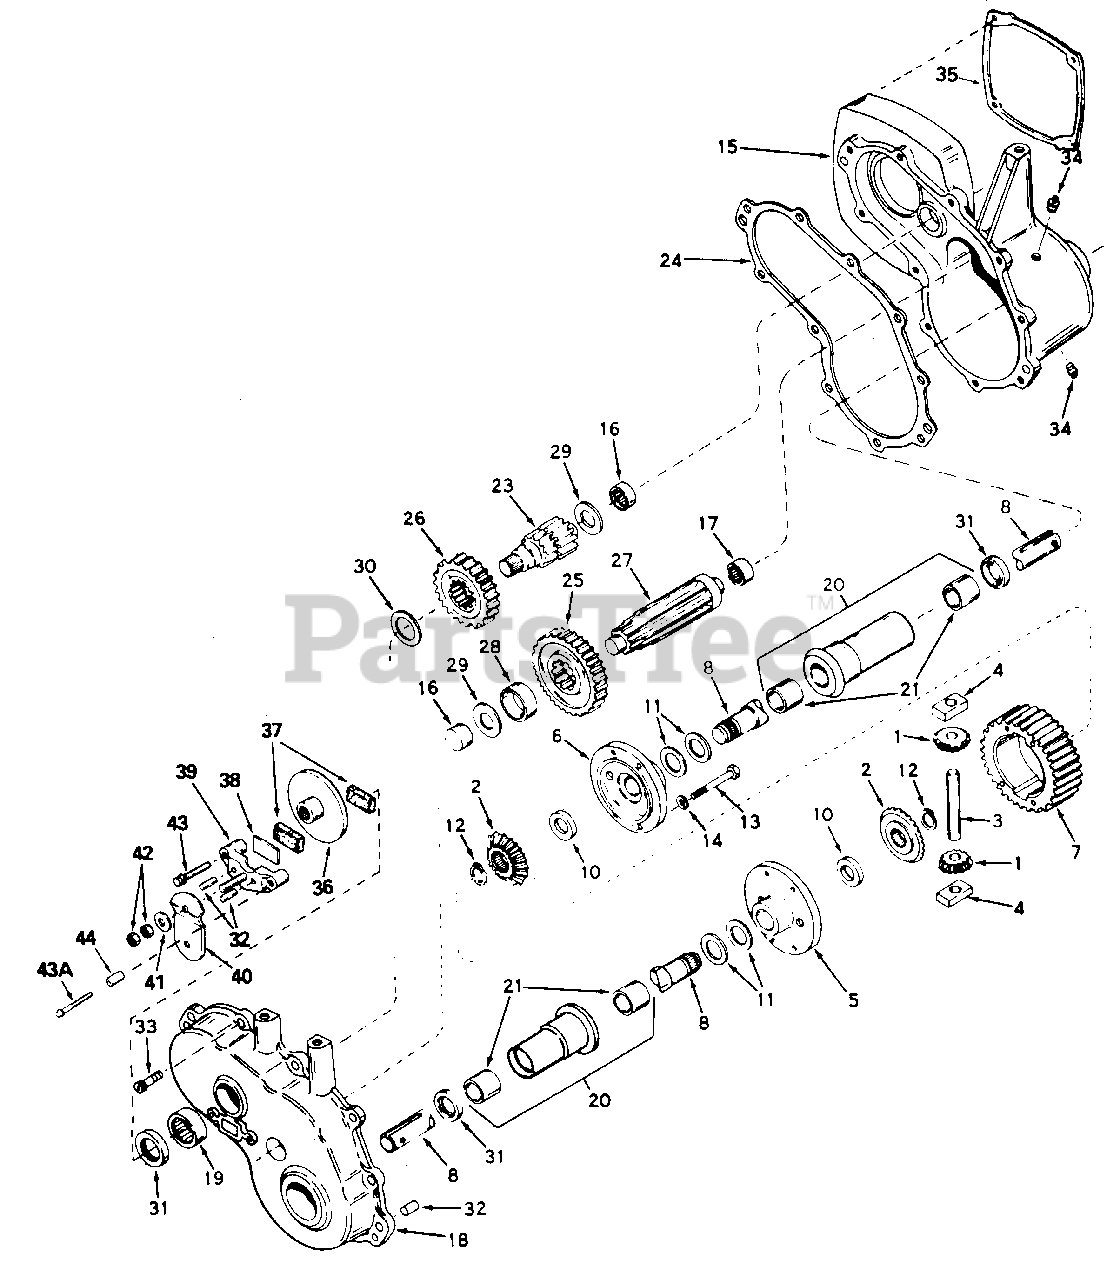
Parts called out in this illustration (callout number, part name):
1	Pinion, Bevel
2	Gear, Bevel
3	Pin, Drive
4	Block, Drive
5	Carrier, Differential
6	Carrier, Differential
7	Gear, Ring
8	Axle (16-1/64" Long)
10	Washer
11	Washer, Thrust
12	Ring, Snap
13	Screw, Hex Hd. 1/4-20 x 2-1/4
14	Lock Washer, 1/4"
15	Case Ass'y.
16	Bearing, Needle
17	Bearing, Needle
18	Cover Ass'y.
19	Bearing, Needle
20	Housing Ass'y., Axle
21	Bushing
23	Shaft, Brake
24	Gasket, Case to Cover
25	Gear, Output
26	Gear, ldler
27	Shaft, Output
28	Spacer
29	Washer
30	Washer
31	Seal, Oil
32	Pin, Dowel
33	Screw, Hex Hd., Self-Tapping, 1/4-20 x 1
34	Plug, Pipe
35	Gasket
36	Disc, Brake
37	Pad, Brake
38	Plate, Brake Pad
39	Holder, Brake Pad
40	Lever, Brake
41	Washer, Flat
42	Lock Nut 5/16-24
43	Screw, Hex Hd., Self-Tapping, 1/4-20 x 1-1/4
43A	Screw, Hex Hd., Self-Tapping, 1/4-20 x 2-1/4
44	Spacer
